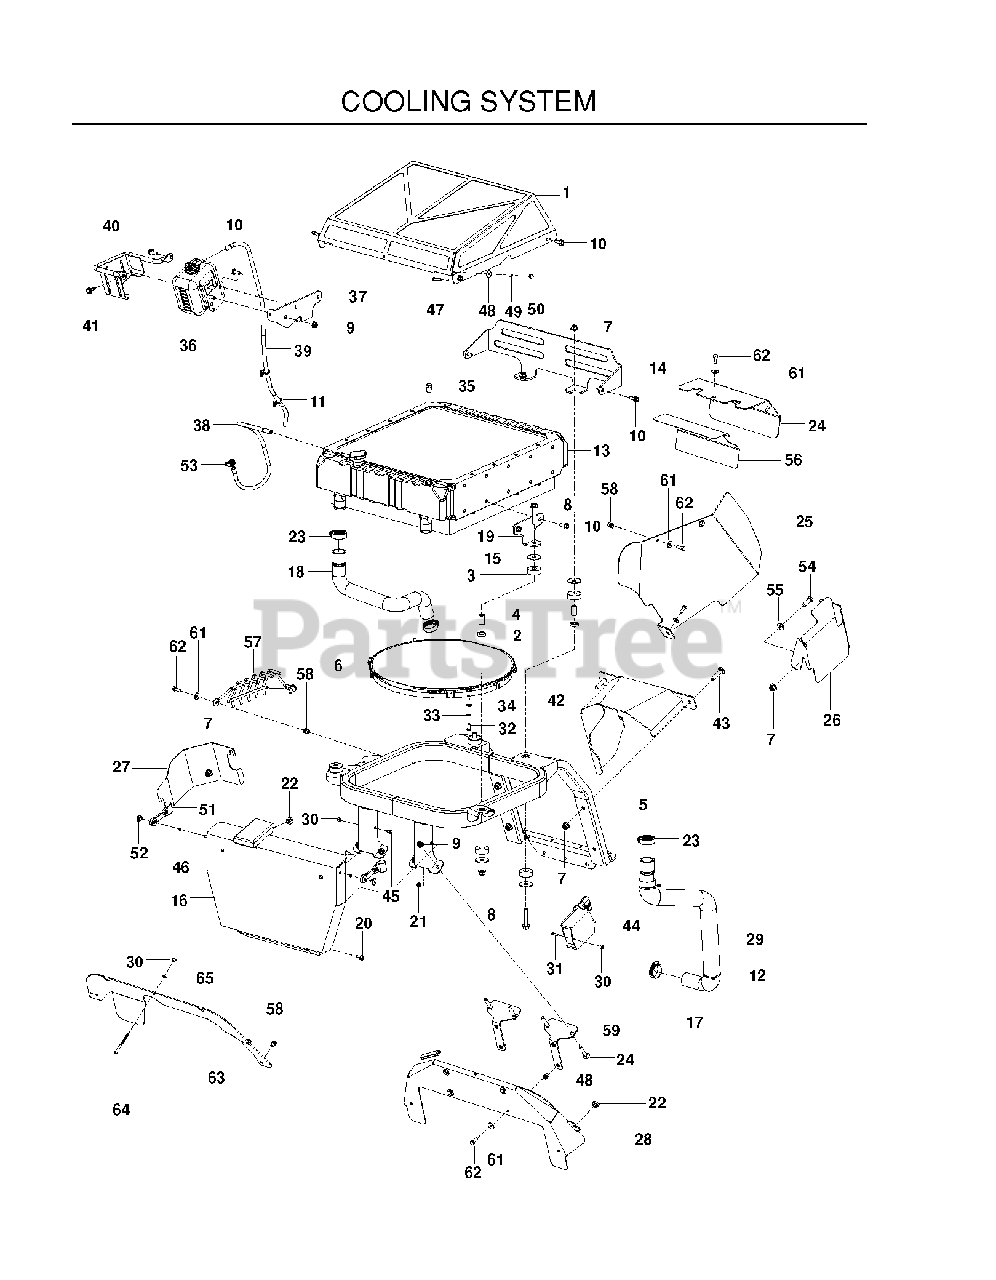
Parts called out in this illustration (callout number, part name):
1	SCREEN, DEBRIS, BLK
2	ISO-MOUNT INSERT
3	ISO-MOUNT BUSHING
4	ISO MT. BUSHING
5	MOUNT, RADIATOR, GRAY
6	FAN, ELECTRIC
7	NUT 3/8-16 HEX FLG NYLOC ZD
8	HHFS 3/8-16 X 2.0 GD 5
9	5/16-18 NYLOC FLANGE NUT
10	HHFS 5/16-18 X 3/4
11	TIE WRAP, 8-3/8", W/CLIP
12	TIE, PLASTIC
14	MOUNT, RADIATOR, REAR-BLK
15	7/16 HD FLAT WASHER
16	Hose Guard with Decals
17	HOSE, RADIATOR, LT
18	HOSE, RADIATOR, RT
19	MOUNT.RADIATOR.FRONT.BLACK
20	SCREW- 1/4-20 X 5/8
21	JAM NUT 1/4C (2 2 PW01)
22	GROMMET, BUMPER
24	GUARD MUFFLER GRAY
25	GUARD.LEFT GRAY
26	GUARD.LH.GRAY
27	GUARD.RT.REAR.GRAY
29	SLEEVE, HOSE
30	NUT 10-24 NYLOC
31	SCREW #10-24 X 5/8
32	HCS 1/4C X 5/8
33	LOCKWASHER 1/4"
34	WASHER 1/4 SAE
35	FITTING, PIPE, 1/4 NPT
36	BOTTLE, OVERFLOW
37	MOUNT, RADIATOR, BLK
38	HOSE, OVERFLOW, UPPER
39	HOSE, OVERFLOW, LOWER
40	GUARD, OVERFLOW, BLK
41	BOLT 5/16-18 X 3/4
42	SHIELD, BELT W/DECAL - GR
43	RHSNB 3/8-16X1-3/4
44	MODULE, FAN REVERSE
45	HCS #10-24 X 1/2
46	WASHER - 3/16 LOCK ZD
47	SCREW #10-24 X 1-1/8 ZD SPEC
49	BSHG .202X.75 LG SPLIT ZD SPEC
50	NUT 10-24 ACORN ZD
51	HOOD LATCH
52	NUT 10-24 WELD PLATED
53	CLAMP, WORM GEAR, NO. 4
54	HCS 3/8-16X1.GRD.5.ZD
55	WASHER 3/8 SAE FLAT
56	BARRIER.HEAT
57	Muffler Guard
58	KNURLED INSERT
60	RHSNB 5/16-18X1 3/4
61	WASHER 1/4 FLAT
62	HCS 1/4C X 3/4 HCS
63	GUARD.FRONT GRAY
64	SCREW.#10-24X2-1/2.GR5.ZD
65	WASHER #10
